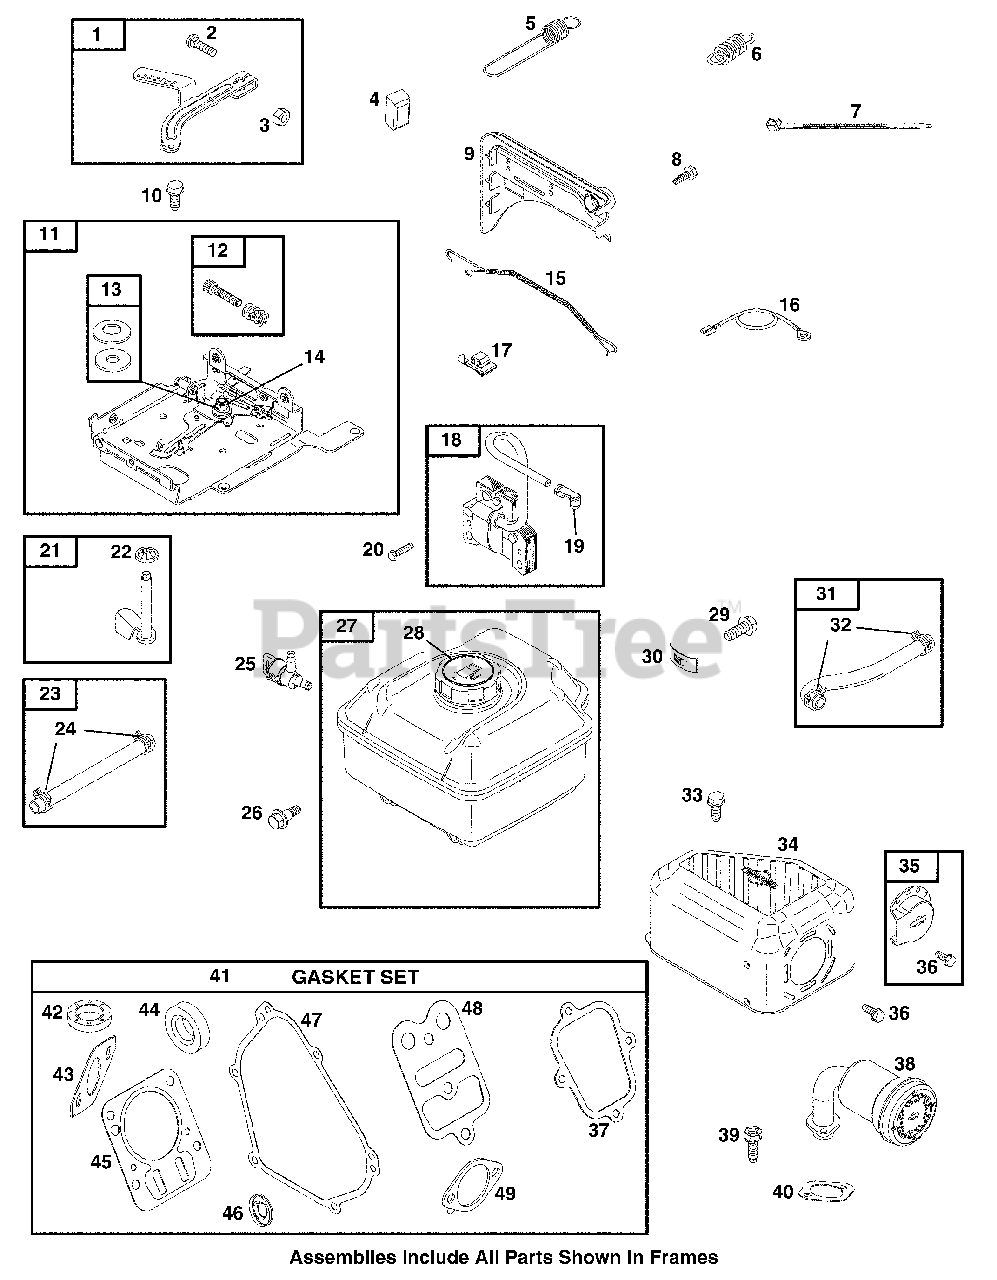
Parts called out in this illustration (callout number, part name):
1	Governor Lever
2	Bolt
3	Nut
4	Control Knob
5	Governor Spring
6	Governor Spring
8	Screw
9	Control Panel
10	Screw
11	Control Bracket
12	Idle Speed Kit
13	Washer Set
14	Nut
15	Spring/Link (Mechanical Governor)
17	Switch-Stop
18	Armature-Magneto
19	Sparkplug Terminal
20	Screw
21	Crank-Governor
22	Retainer-Governor Shaft
23	Fuel Line
24	Clamp-Hose
25	Valve-Shutoff
26	Screw
27	Fuel Tank
28	Fuel Tank Cap
29	Screw
31	Fuel Line (Molded)
32	Clamp-Hose
33	Screw
34	Guard-Muffler
35	Deflector-Muffler
36	Screw
37	Gasket-Rocker Cover
38	Muffler-Exhaust
39	Screw
40	Gasket-Exhaust
41	Gasket Set
42	Oil Seal
43	Intake Gasket
45	Cylinder Head Gasket
46	Seal-Valve
47	Crankcase Gasket
48	Cylinder Head Plate Gasket
49	Air Cleaner Gasket
